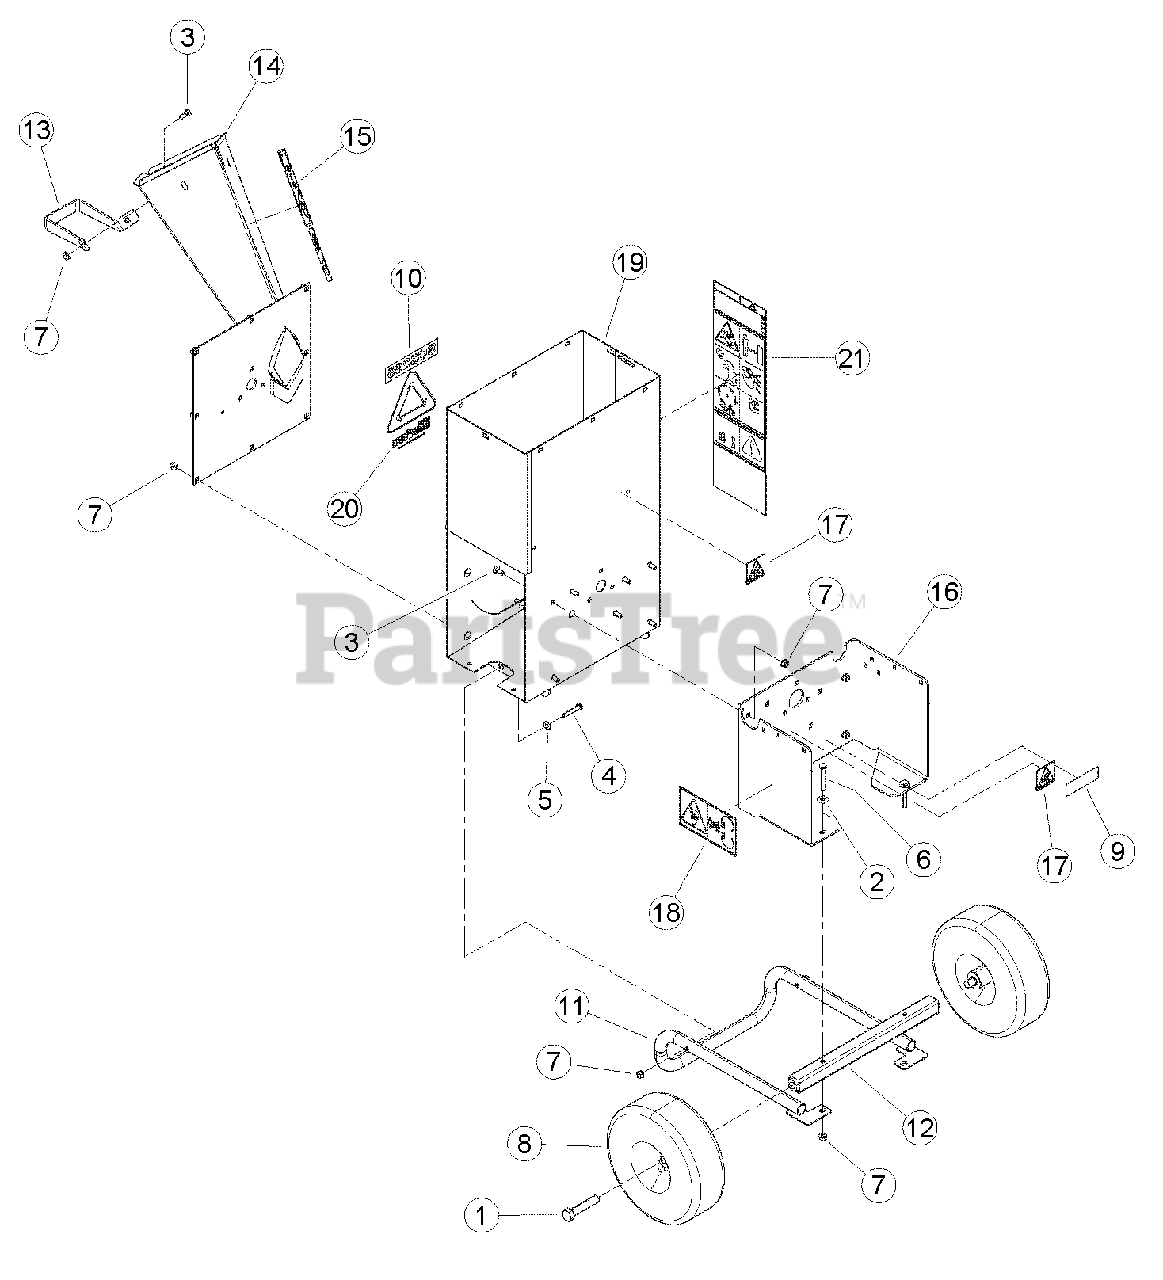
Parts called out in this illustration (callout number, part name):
1	BOLT, 5/8 X 3 HEX HD GR5 ZP
2	WASHER, 5/16 FLAT ZP
3	BOLT, 5/16 X 3/4 CRG GR5 NC ZP
4	BOLT, 5/16-18 X 1-3/4 HEX HD GR5 ZP
5	WASHER, 5/16 SAE FLAT ZP
6	BOLT, 5/16-18 X 2-1/4 HEX HD GR5
7	NUT, 5/16 FLANGE TOPLOCK
8	WHEEL ASSY, 410/350-4
9	DECAL, SERIAL NUMBER
10	DECAL, MODEL SC3206
10	DECAL, MODEL SC3265
10	DECAL, MODEL SC3305
10	DECAL, MODEL SC3305E
10	DECAL, MODEL SC3342
11	WELDMENT, SUPPORT LEG LONG
11	WELDMENT, SUPPORT LEG SHORT (SC3206 ONLY)
12	WELDMENT, AXLE 3" CHIPPER
13	HANDLE, CHIPPER CHUTE 3"
14	ASSEMBLY, 3" FRONT PLATE, SERVICE PART
15	DECAL, 3" CHIPPER CHUTE
16	ASSEMBLY, 3" CHIPPER BASE, SERVICE PART
17	DECAL, SHIELD DANGER ISO
18	DECAL, BLADE DANGER ISO
19	ASSEMBLY, 3" WIDE BODY, SERVICE PART
19	ASSEMBLY, 3" NAROW BODY, SERVICE PART - SC3206 ONLY
20	DECAL, SHRED IT
21	DECAL, 3" CHIPPER BODY SIDE
